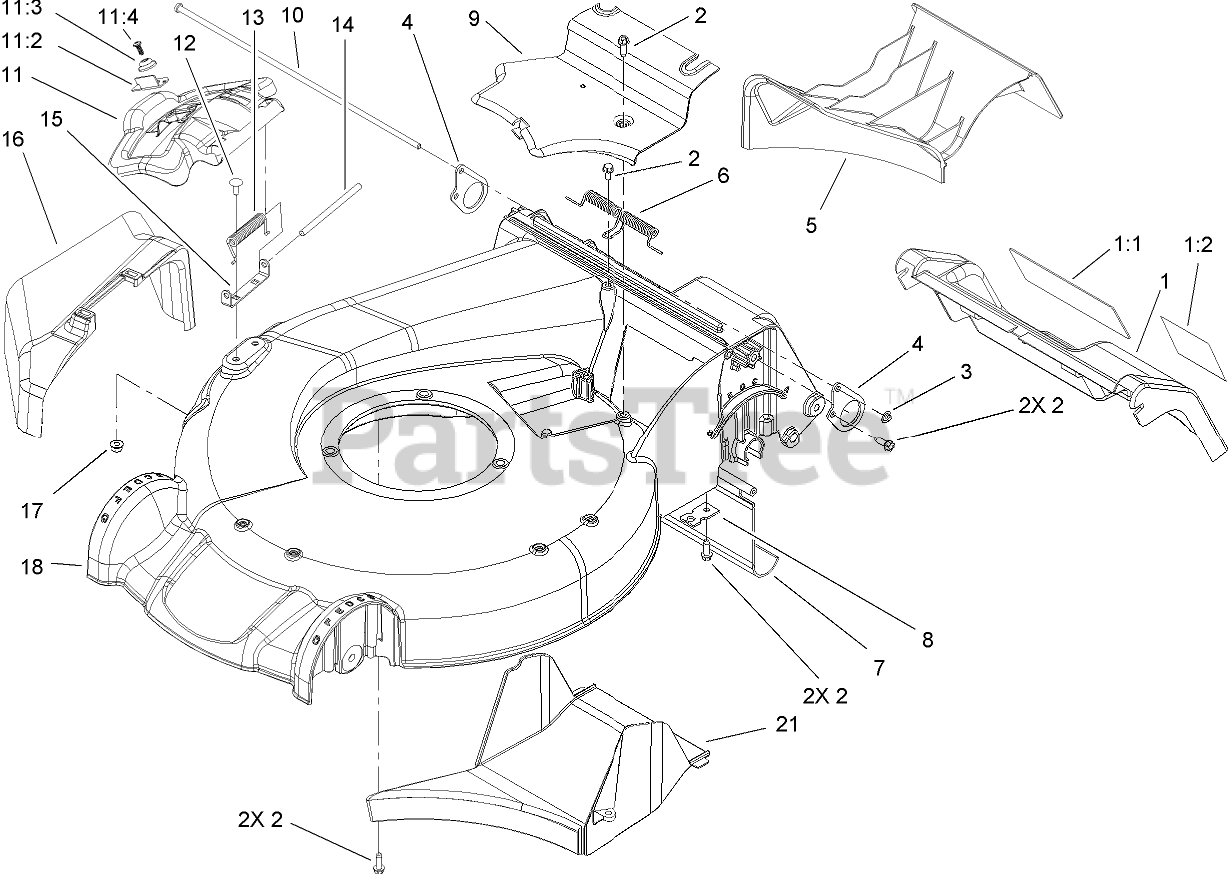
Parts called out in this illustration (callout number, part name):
1	DOOR-SERVICE
1:1	DECAL-WARNING
1:2	DECAL-WARNING
2	SCREW-HWHTF
3	NUT-SPEED
4	PLATE-SUPPORT, DOOR
5	MULCH PLUG ASM
6	Spring-Door, Rear
7	SHIELD-TRAILING
8	BRACKET-CABLE, TRACTION
9	COVER-BELT
10	ROD-SUPPORT, DOOR
11	DISCHARGE DOOR ASM
11:2	LATCH-DOOR
11:3	CAP-DOOR
11:4	SCREW-PLASTITE
12	SCREW-CARR
13	SPRING-TORSION
14	ROD-COVER
15	BRACKET-COVER
16	CHUTE-DISCHARGE, SIDE
17	NUT-HHF
18	HOUSING ASM
21	TUNNEL-DISCHARGE
